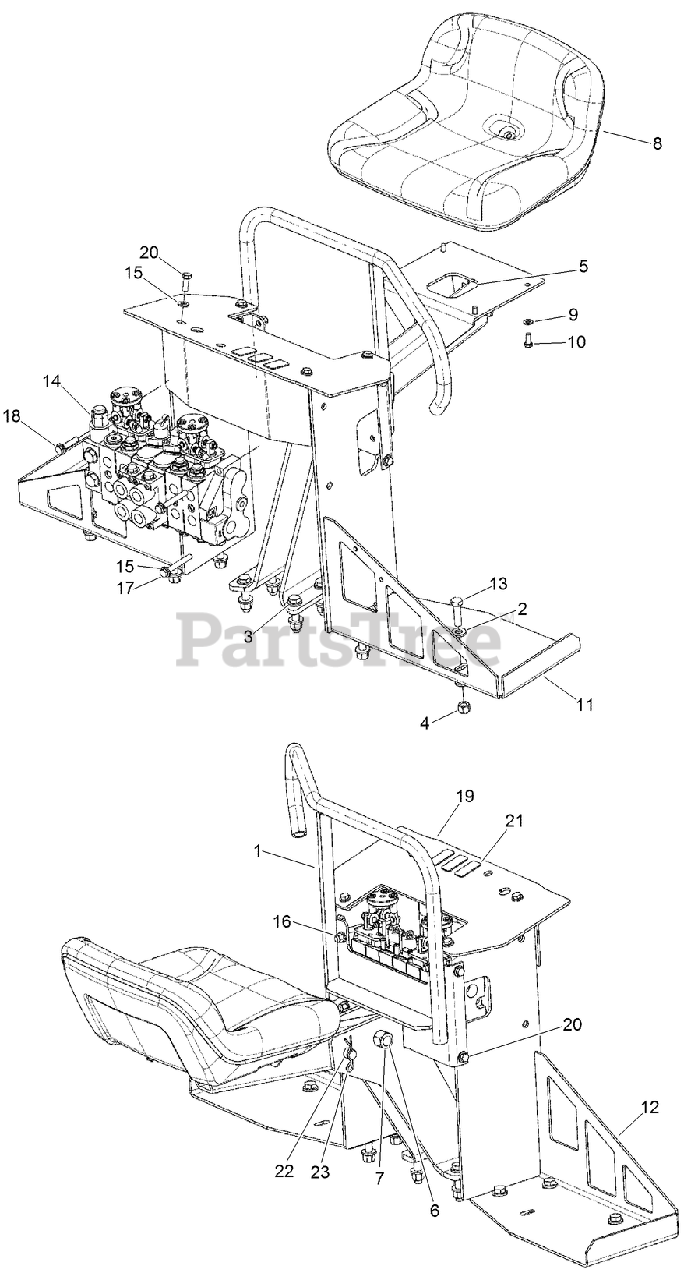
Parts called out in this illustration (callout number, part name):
1	WELDMENT, CONSOLE - Valve and Seat Mounting
2	WASHER-FLAT
3	SCREW-HH
4	NUT-HEX
5	POST-Seat, Backhoe
6	BOLT-Hex Hd 0.750 x 3.75 GR8 ZND
7	NUT-HEX LOCK
8	SEAT-BLACK, LOW-BACK
9	WASHER-FLAT
11	WELDMENT, GUARD - Foot, LH
12	WELDMENT, GUARD - Foot, RH
13	BOLT-Hex Hd 1/2 x 1-3/4 GR5 ZND
14	VALVE-BACKHOE, 6 SPOOL
15	WASHER-FLAT
16	NUT-HEX
17	BOLT-HH
18	BOLT-Hex Hd .375 x 1.75 GR5 ZND
19	COVER - Valve Top, Weldment
20	SCREW-HH
21	BLANK-SWITCH, ROCKER
22	PIN-CLEVIS
23	PIN-HAIR COTTER, INT
